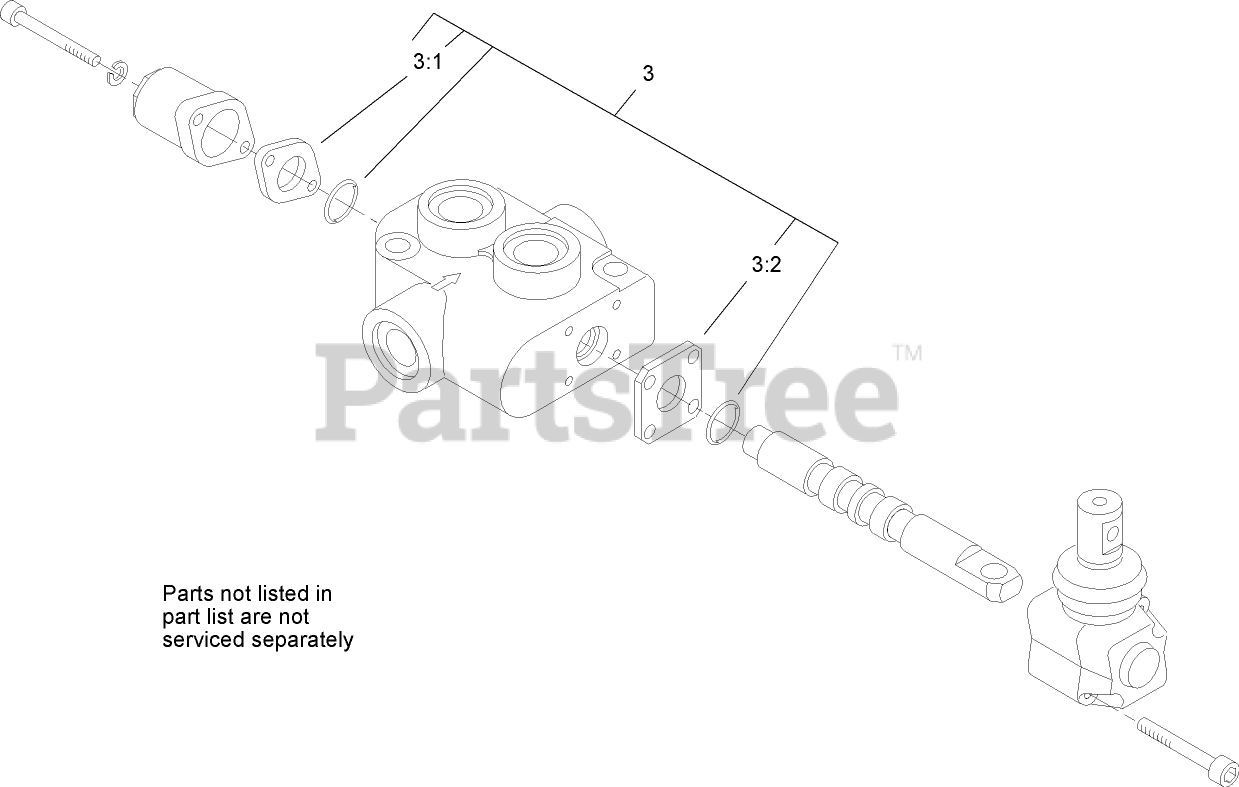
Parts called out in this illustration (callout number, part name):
3	SEAL KIT
3:1	GASKET
3:2	GASKET
